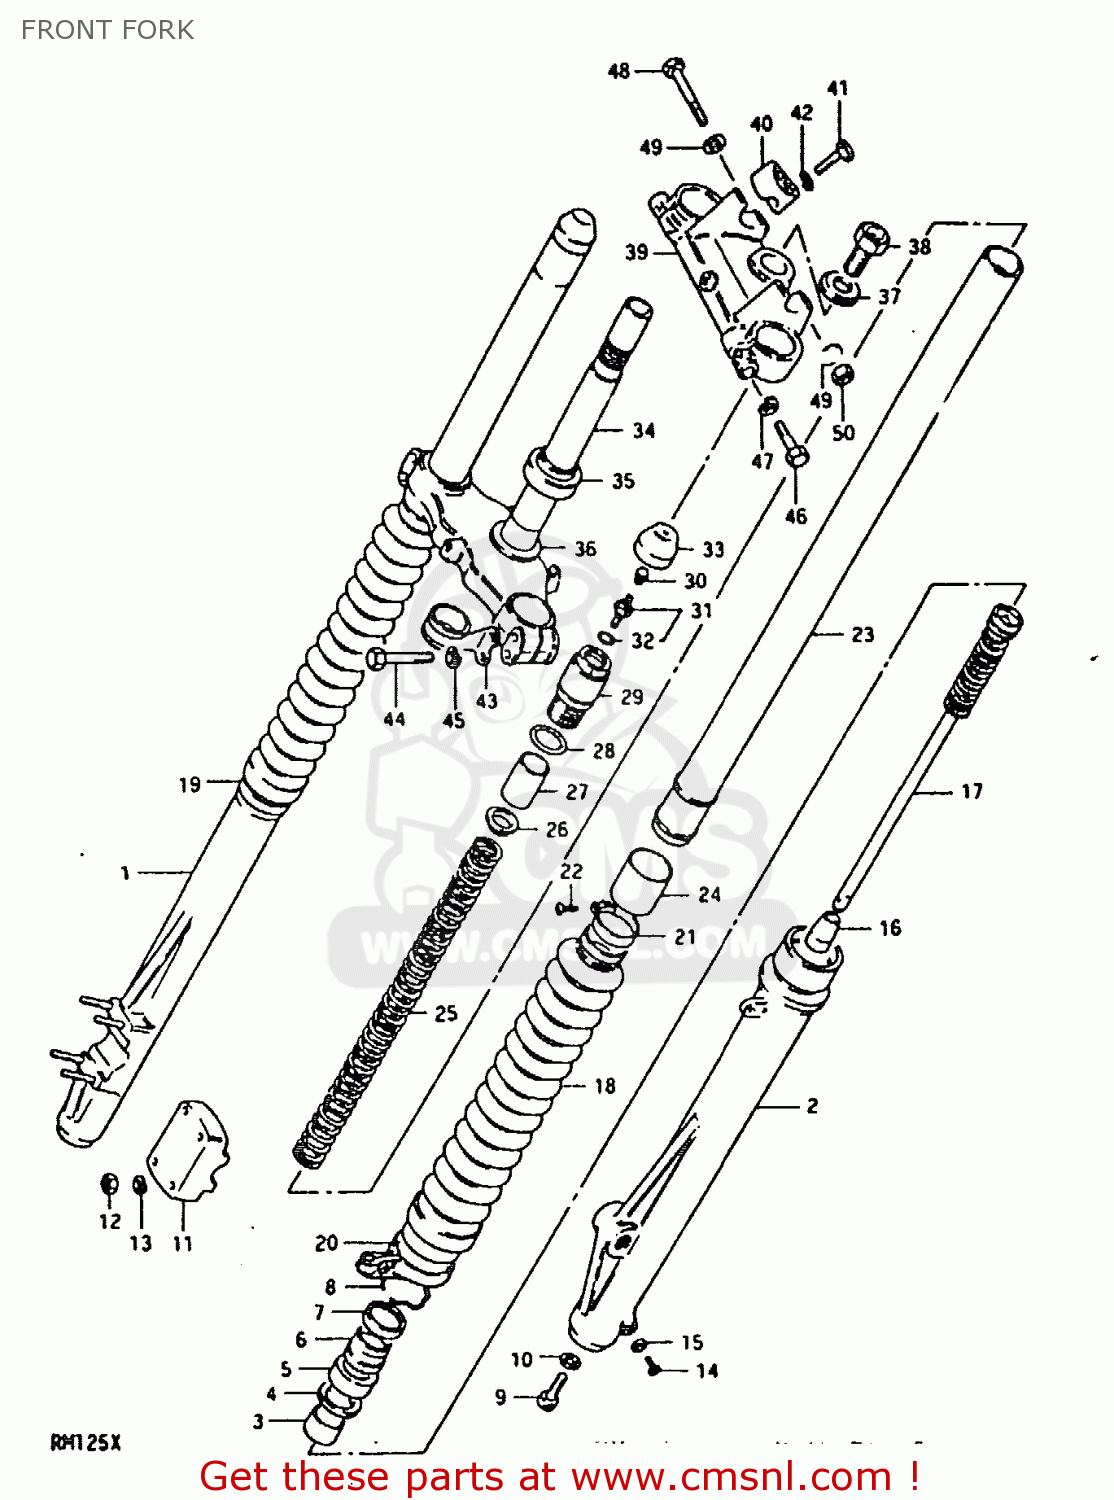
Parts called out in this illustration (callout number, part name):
1	TUBE,OUTER,RIGHT
2	TUBE,OUTER,LEFT
3	METAL,SLIDE
4	WASHER(40X50X2.3)
5	SEAL,OIL
6	SEAL,DUST
7	CASE,DUST SEAL
8	RING,STOPPER
9	BOLT,CYLINDER
10	GASKET,CYLINDER (NAS)
11	HOLDER,AXLE
12	NUT
13	LOCK WASHER
14	SCREW
15	GASKET,DRAIN,PLUG (NAS)
16	PIECE,OIL LOCK
17	CYLINDER,FRONT FORK
18	BOOT
19	BAND,FRONT FORK COVER BOOT
20	BAND,FRONT FORK COVER BOOT
21	BAND,BOOT
22	SCREW 4X10
23	TUBE,FORK,INNER
24	PISTON
25	SPRING,FRONT FORK
26	GUIDE
27	SPACER,FRONT FORK SPRING
28	O RING
29	CAP,FORK INNER TUBE
30	CAP,VALVE AIR
31	VALVE
32	O RING
33	CAP
34	STEM,STEERING
35	BEARING
36	WASHER,THRUST
37	WASHER
38	BOLT
39	HEAD,STEERING STEM
40	HOLDER,HANDLEBAR
41	BOLT
42	LOCK WASHER
43	CLIP,CABLE
44	BOLT 8X45
45	LOCK WASHER
46	BOLT
47	LOCK WASHER
48	BOLT 8X50
49	WASHER
50	NUT
